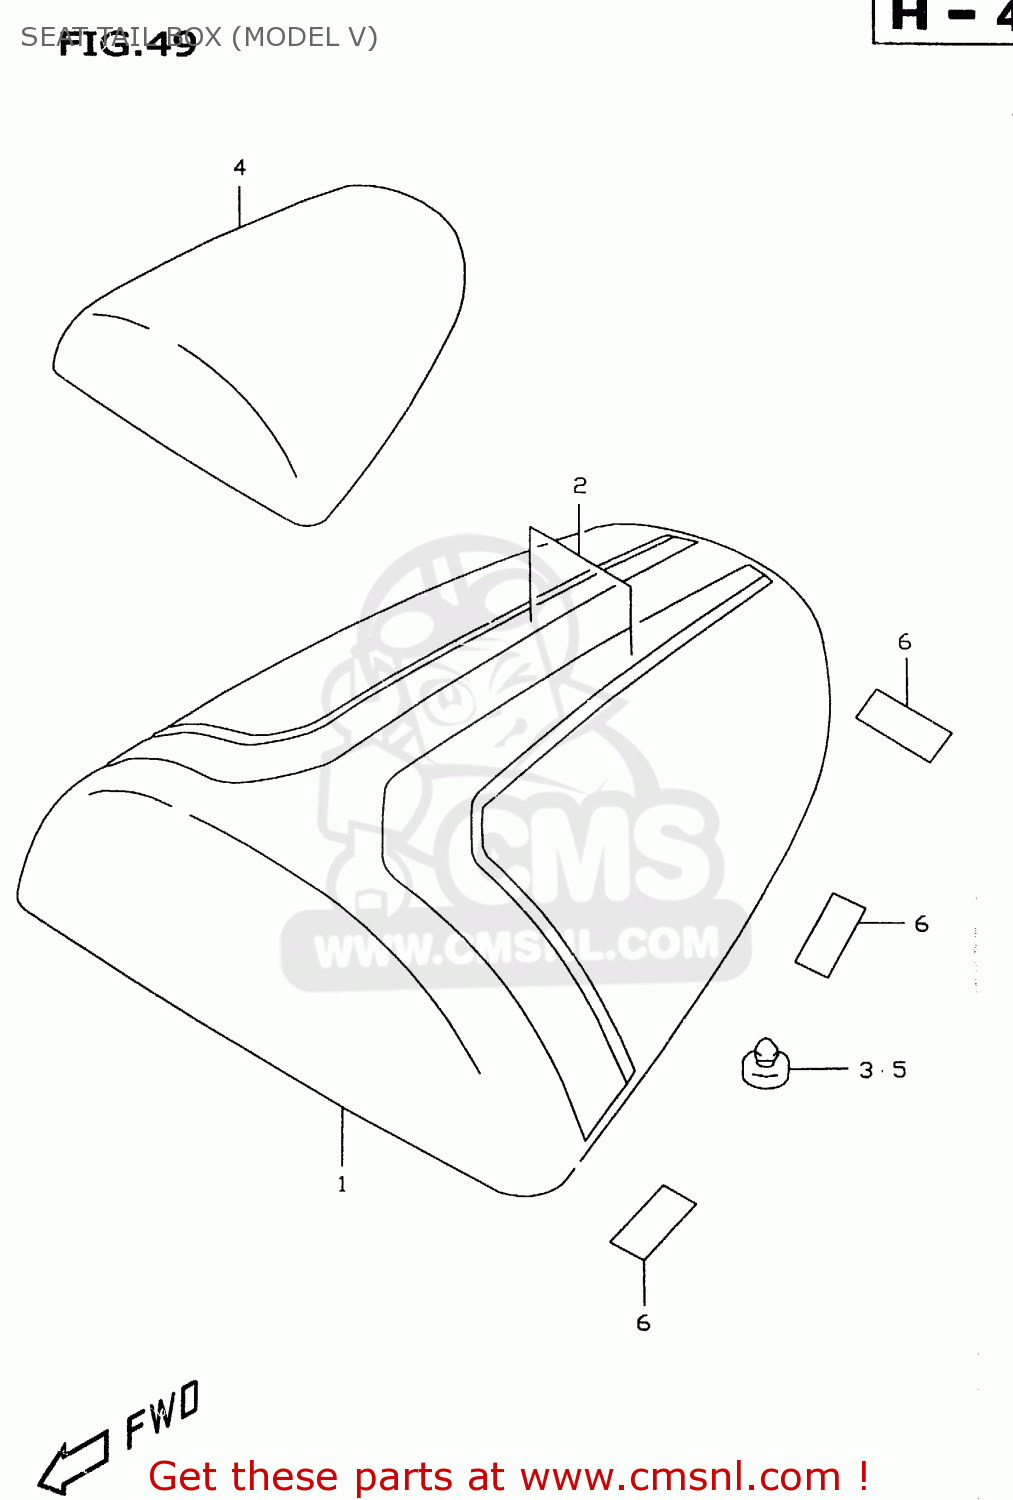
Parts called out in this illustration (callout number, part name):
1	BOX ASSY,SEAT TAIL(WHITE)
2	TAPE SET,BOX SEAT TAIL
3	CUSHION(11.5X22X20)
4	BOX,SEAT TAIL(GRAY)
5	CUSHION(11.5X22X20)
6	PROTECTOR SET,SEAT TAIL BOX
